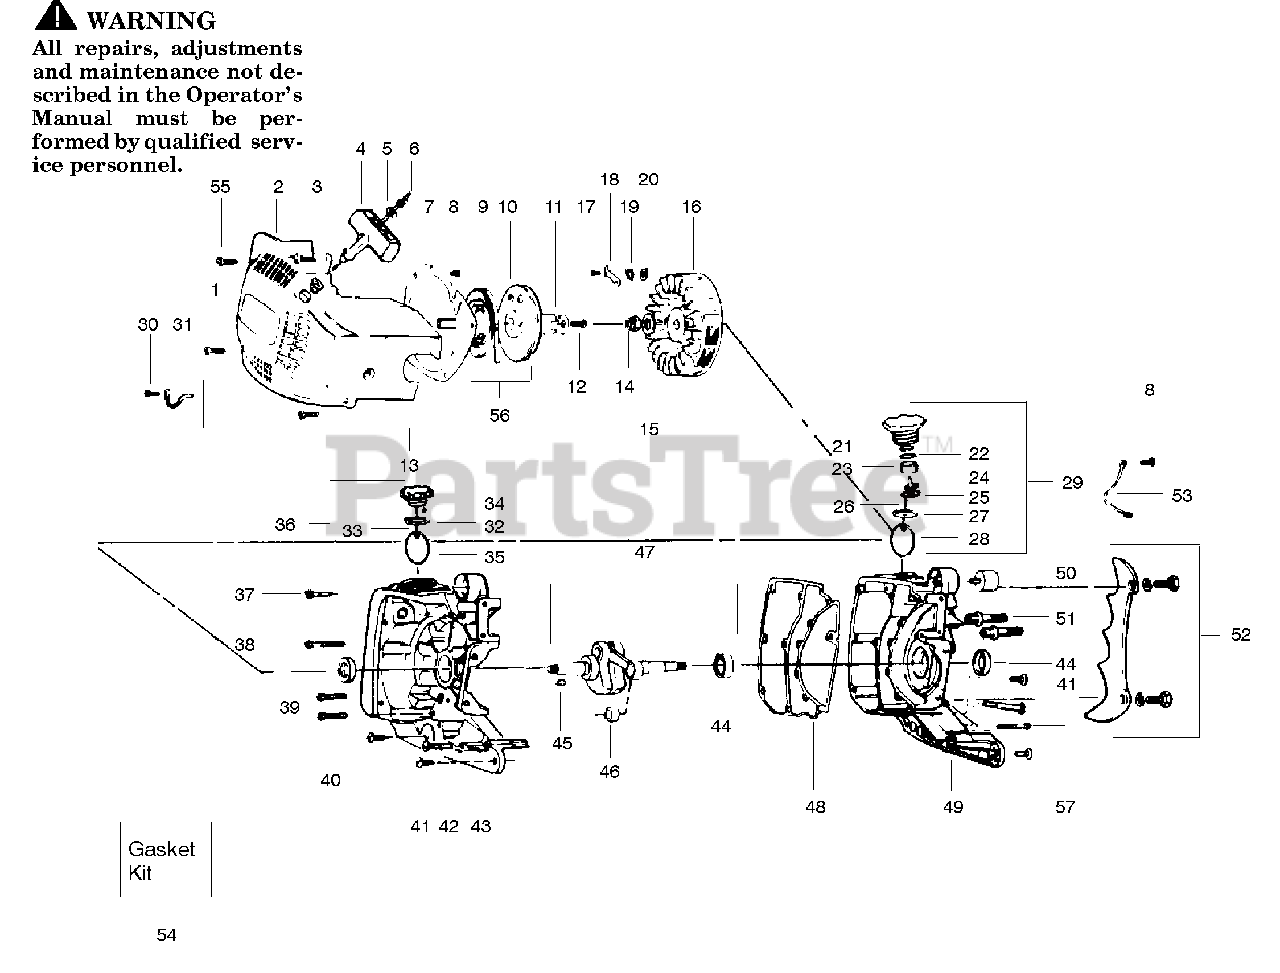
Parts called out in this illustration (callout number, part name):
2	Starter Cover & Shell Ass'y.
4	Starter Handle
6	Starter Cord
7	Baffle Plate
9	Rewind Spring
10	Starter Pulley
13	Starter Ass'y.
16	Flywheel
24	Umbrella Valve
25	Cover Gas Cap
26	Bead Chain
28	Retainer
29	Gas Cap Ass'y.
31	Retainer Wire
32	"O" Ring
33	Bead Chain
35	Retainer
36	Oil Cap Ass'y.
43	Crankcase Half
44	Main Bearing
45	Flywheel Key
47	Crankshaft Ass'y.
49	Crankcase Ass'y. Drive Side
50	Shock Absorber
51	Bar Mtg. Studs
52	Pivot Grip Kit
53	Ground Wire
54	Gasket Set
56	Pulley & Spring Kit
